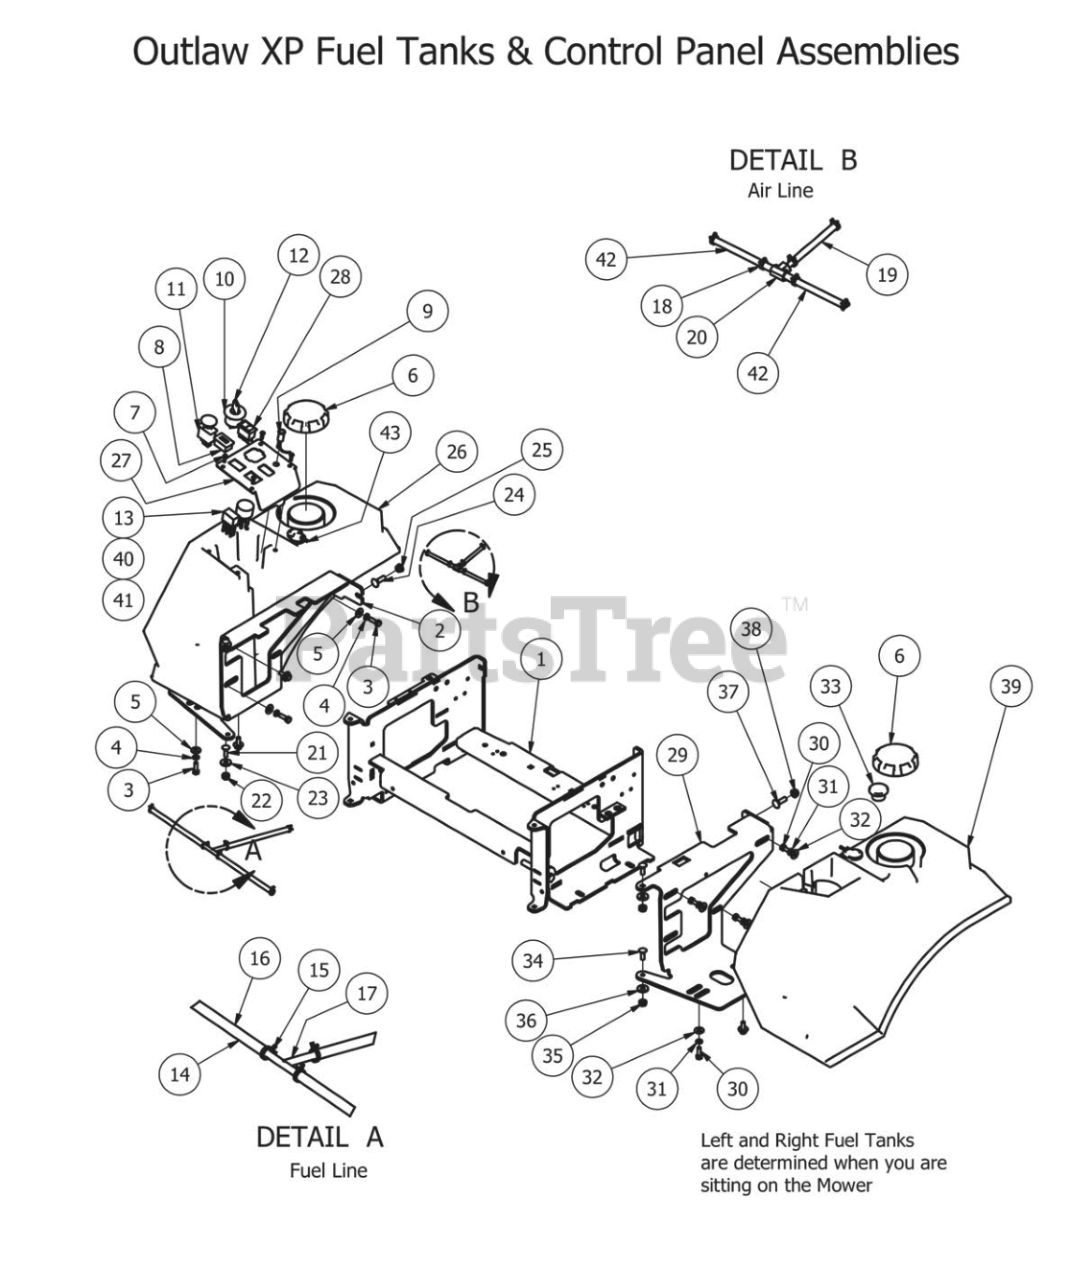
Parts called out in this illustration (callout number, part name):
1	Outlaw Seat Bracket 2012
2	Outlaw Tank Support 2012 (Right)
3	5/16" x 1" Bolt
4	5/16" Lock Washer
5	5/16" Flat Washer
6	3.5" Tethered Fuel Cap
7	10-32 x 3/8" Button Socket Head Bolt
8	Tachometer
10	Ignition Switch
11	PTO Engager
12	Ignition Key
13	Wiring Harness- FX-850V kawasaki Outlaw
14	Fuel line Assembly -31 Outlaw
15	1/4 fuel clamp
16	1/4" fuel line hose
17	fuel line T
18	3/16 vinyl clamp
19	3/16 vinyl tubing
20	Brass fuel line T
21	5/16" x 1" Carriage Bolt
22	5/16-18 Nylon Flange Nut
23	.360 ID Plastic Washer
24	3/8" x 1 1/4" Carriage Bolt
25	3/8" Nylock Flange Nut
26	2012 EPA Fuel Tank - XP-XTRM - Right
27	Outlaw Control Panel (Rocker Switch)
28	Rocker Deck Lift Switch - 2011
29	Tank Support 2012 Outlaw (Left)
30	5/16" x 1" Bolt
31	5/16" Lock Washer
32	5/16" Flat Washer
33	Fuel Gauge-Tanks w/downtube
34	5/16" x 1" Carriage Bolt
35	5/16-18 Nylon Flange Nut
36	.360 ID Plastic Washer
37	3/8" x 1 1/4" Carriage Bolt
38	3/8" Nylock Flange Nut
39	2012 EPA Fuel Tank- XP-XTRM- Left
40	Wiring Harness 36hp Vanguard Outlaw
41	Relay Terminal
42	1/4" Vinyl Tubing - Black
43	Rollover Valve-White
